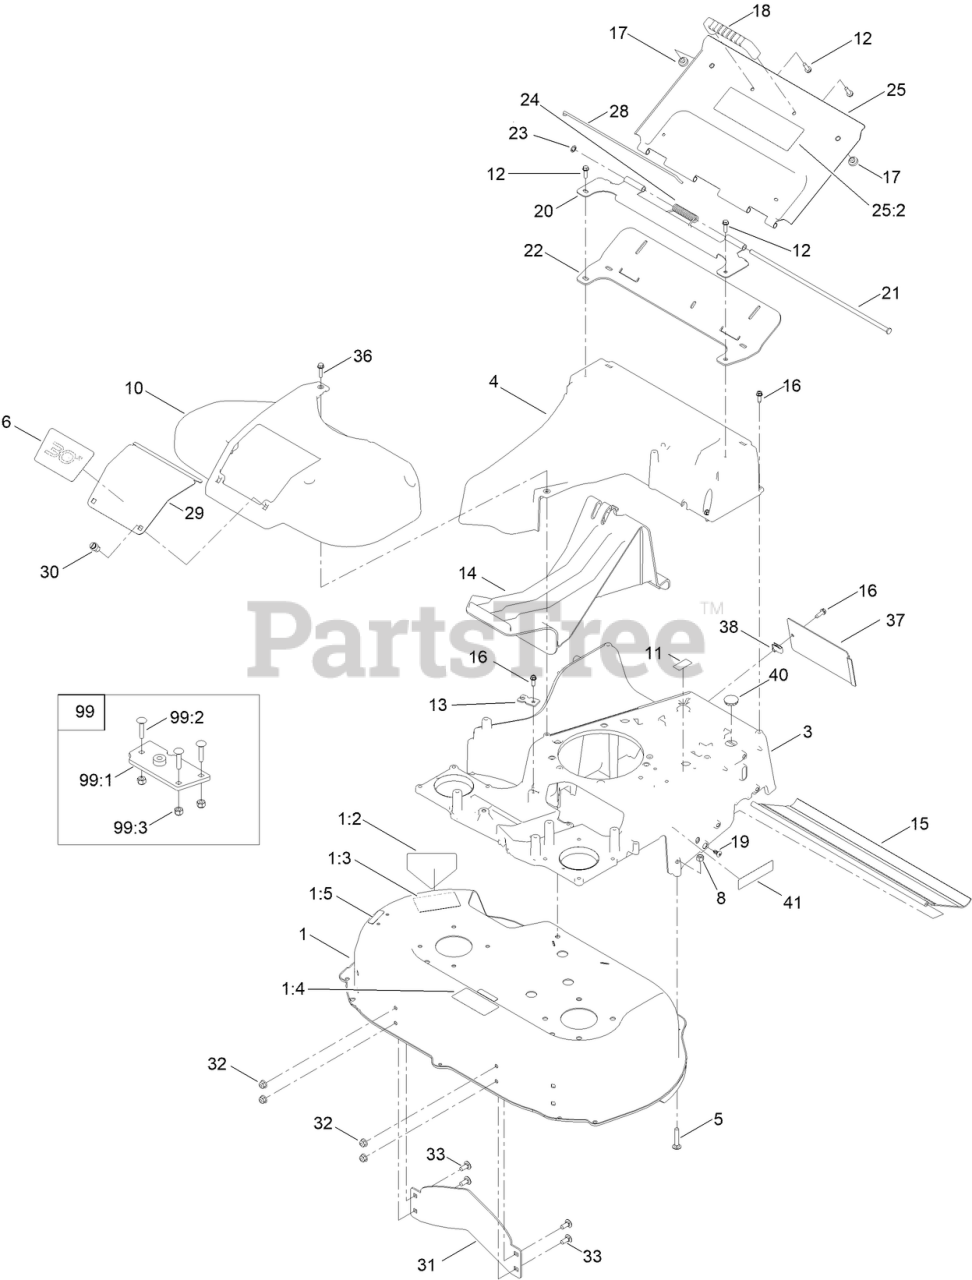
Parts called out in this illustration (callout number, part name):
1	DECK ASM
1:2	DECAL-DANGER
1:3	DECAL-DANGER, CE
1:5	DECAL-WARNING
3	FRAME-30
5	BOLT-CAR
6	DECAL-30 INCH
8	NUT-LOCK, NI
10	COVER-BELT
11	DECAL-PATENT
12	SCREW-HWH
13	BRACKET-CABLE, TRACTION
14	PLUG-MULCH
15	SHIELD-TRAILING
16	SCREW-HWHTF
17	BUMPER
18	HANDLE-DOOR
19	SCREW-PTH
20	BRACKET-HINGE
21	PIN-HINGE
22	SEAL-DOOR
23	RING-RETAINING
24	SPRING-TORSION, COVER
25	REAR DOOR ASM
25:2	DECAL-WARNING
28	CLIP-SEAL
29	DOOR-ACCESS
30	FASTENER
31	BAFFLE-CONTROL
32	NUT-HF, NI
33	SCREW-CARR
36	SCREW-HWHTF
37	COVER-FRAME
40	PLUG-BUTTON
41	DECAL-ARRESTOR, SPARK
99	FRAME PLATE KIT
99:1	PLATE-FRAME
99:2	SCREW-CARR
99:3	NUT-LOCK, NI
